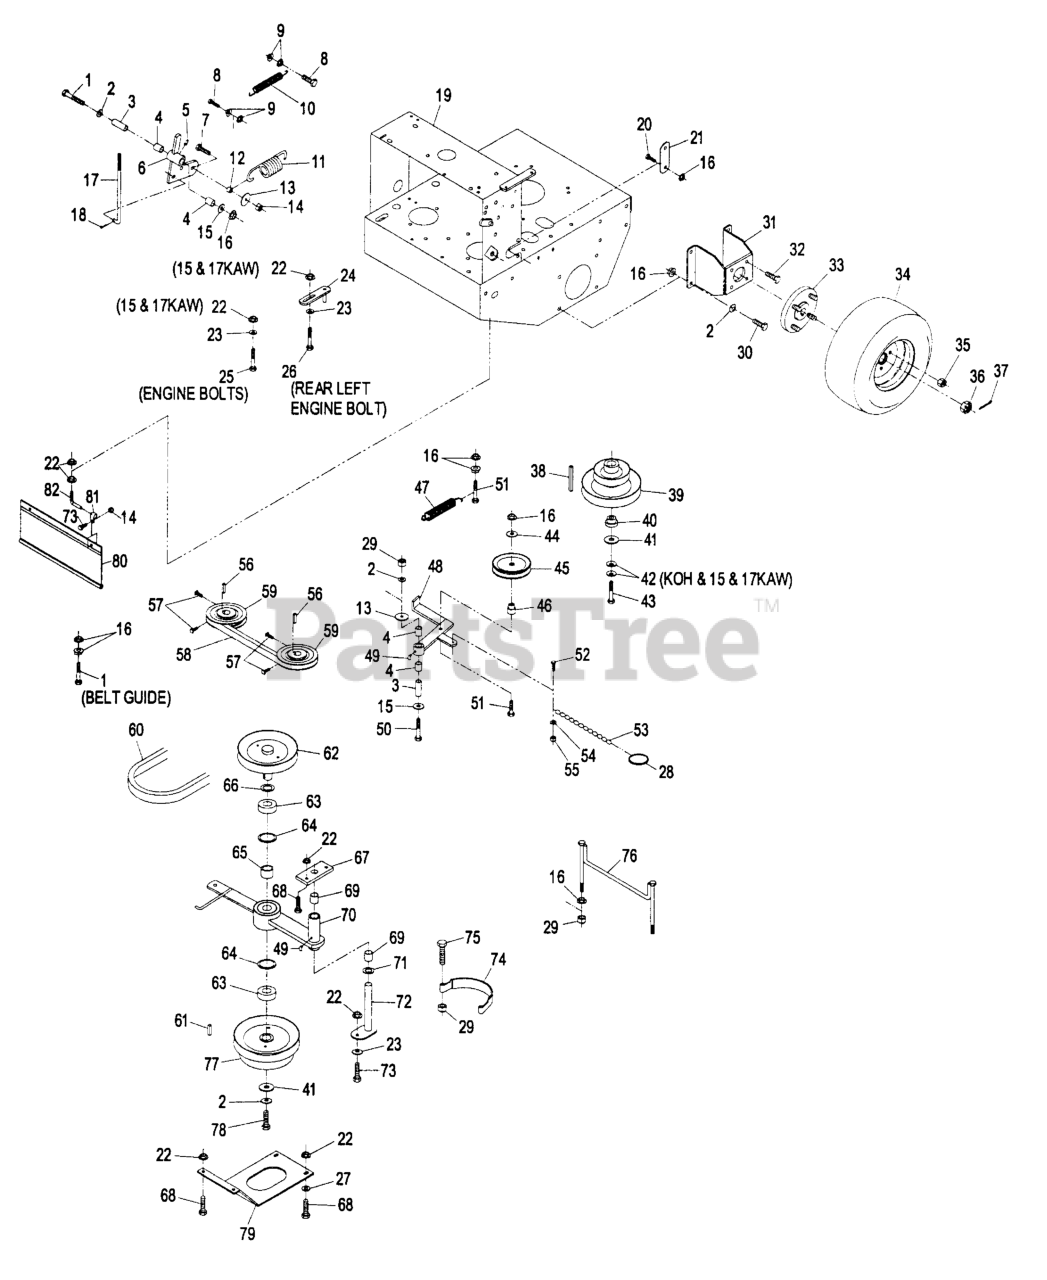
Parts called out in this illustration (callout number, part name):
2	WASHER-BELLEVILLE
3	BUSHING
4	SLEEVE-BEARING
10	SPRING,EXTENSION
11	SPRING,BELT TENSION
12	SPACER,CLUTCH ANCHOR
17	LINKAGE,LOWER
18	PIN-COTTER
21	ARM-LIFT, DECK
23	WASHER-SPRING
24	GUIDE-BELT
28	RING-SPLIT
31	WLD,MOTOR MOUNT 36
34	WHEEL AND TIRE ASM
37	PIN-COTTER
38	KEY,MACH 1/4X1/4X2-5/8
39	SHEAVE,DRIVE
40	BUSHING,CLUTCH KEEPER
42	WASHER-SPRING
46	BUSHING-IDLER
47	SPRING-EXTENSION
49	1481
52	SCREW-HSH
53	CHAIN-LINK, TWIST
57	SCREW-SET
59	SHEAVE ASM
60	BELT,BLADE CLUTCH
62	SHEAVE,6.13 W/SHAFT
63	BEARING,CLUTCH SHAFT
65	SPACER,CLUTCH BEARING
66	WASHER-SPACER
67	PLATE-CLUTCH PIVOT
69	SLEEVE,BEARING
71	WASHER-SPACER
72	WLD,PIN PIVOT
74	BAND,BRAKE BLADE
76	GUIDE - BELT
77	SHEAVE,6.13 W/HUB
78	SCRW,CAP HH
79	PLATE-GUARD
81	CLIP-LOOM
82	MOUNT,DRAG SHIELD
